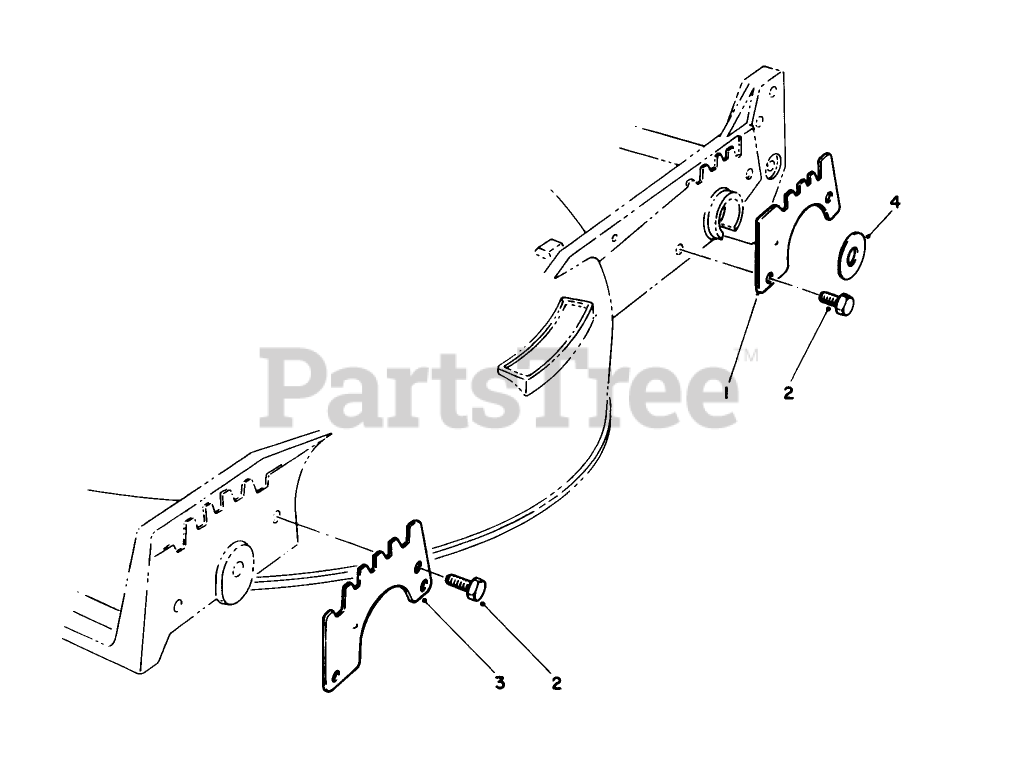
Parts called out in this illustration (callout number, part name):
1	WEAR PLATE,REAR
2	SCREW-HWH
3	WEAR PLATE
4	PIVOT WASHER
